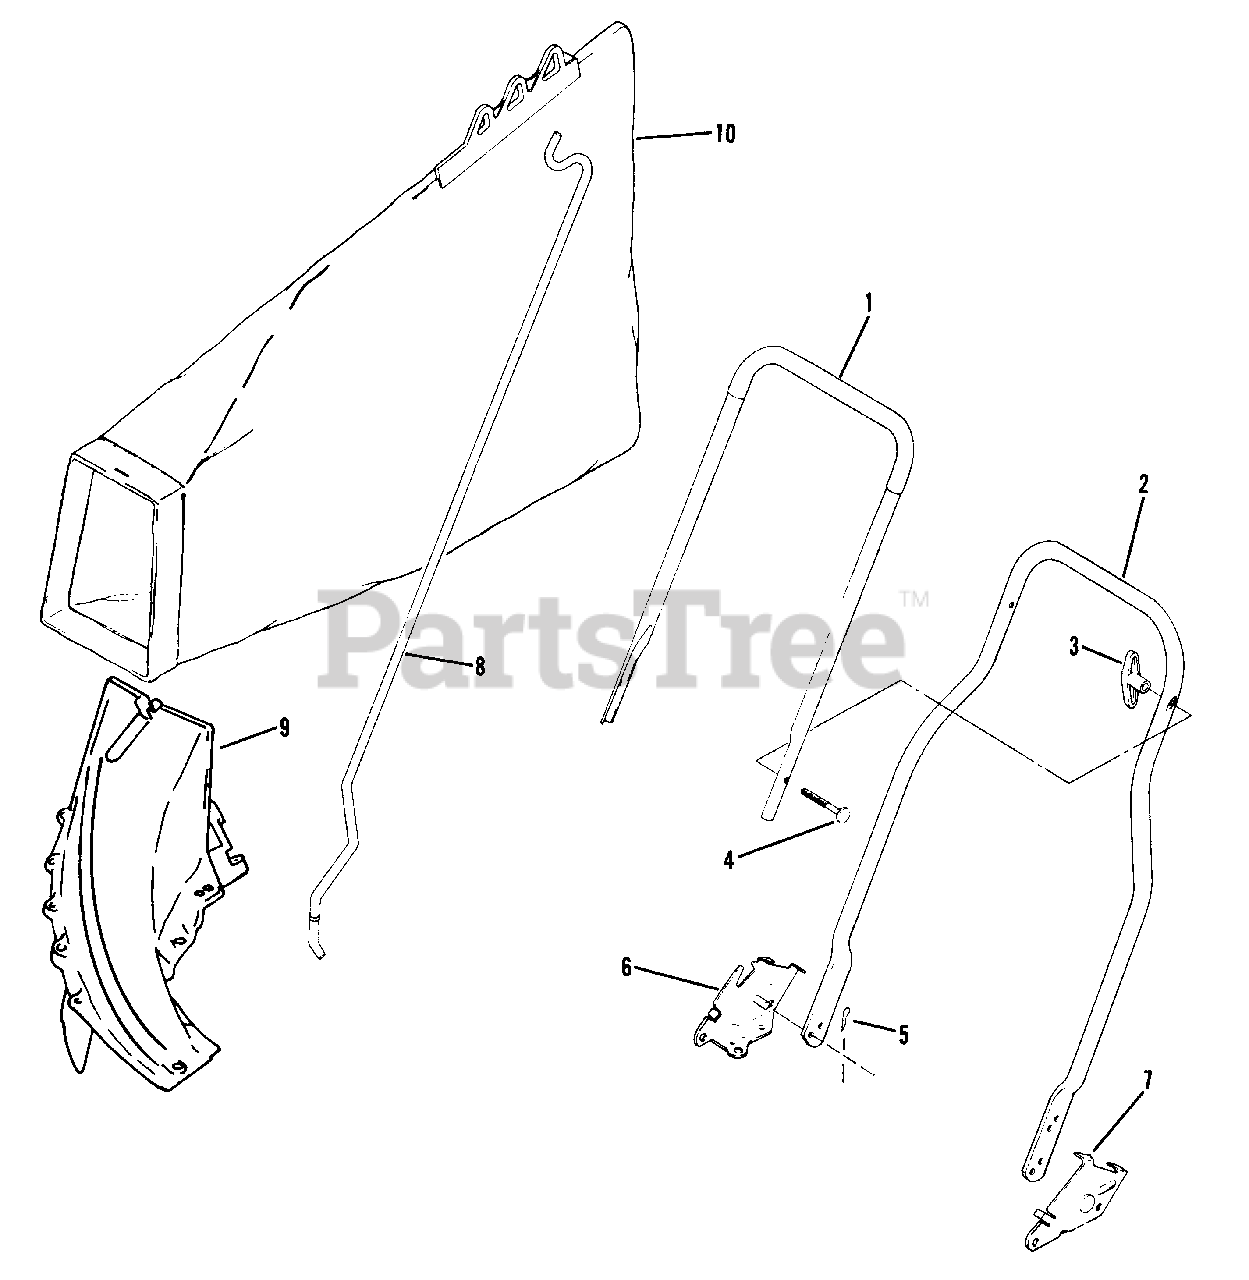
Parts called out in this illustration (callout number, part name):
1	Top Handle & Grip Assembly
2	HandleSection-Bottom
2	Handle Section-Bottom
3	Knob
4	Screw
5	Hair Pin
6	Handle Bracket-R.H.
7	Handle Bracket-L.H.
8	Rod-Grass Bag
9	Chute Assembly
10	Bag Assembly
